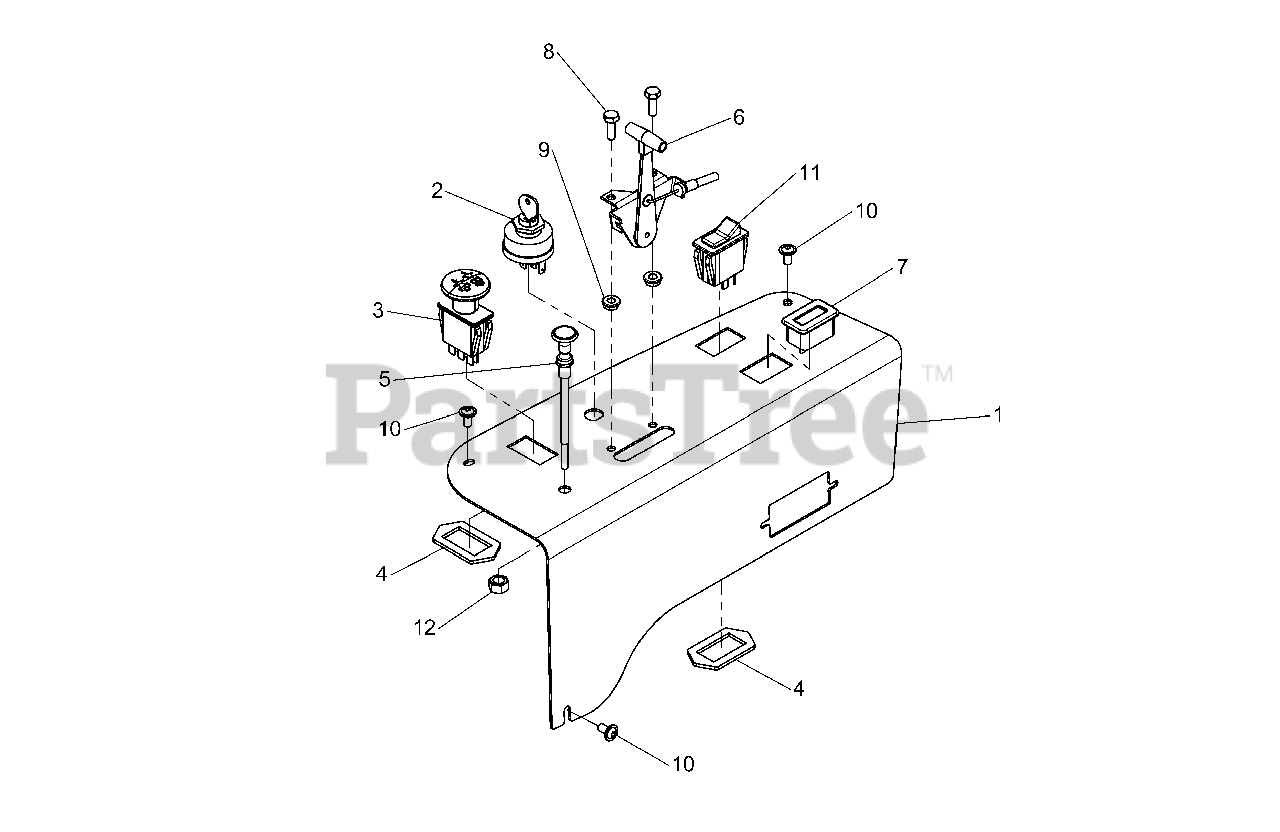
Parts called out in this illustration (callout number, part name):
1	CONTROL PANEL
2	SWITCH, Ignition, Complete (See Electrical Group for parts breakdown)
3	SWITCH, PTO
4	SWITCH RETAINER RING
5	CABLE, CHOKE CONTROL
6	CABLE, Throttle, 40"
7	HOUR METER, DIGITAL
8	BOLT, 1/4-20 X 3/4"
9	NUT, 1/4-20 Hex Serrated Flange
10	SCREW, Allen Head, 1/4-20 x 1/2
11	SWITCH, Headlight
12	NUT, 3/8-24 Hex
